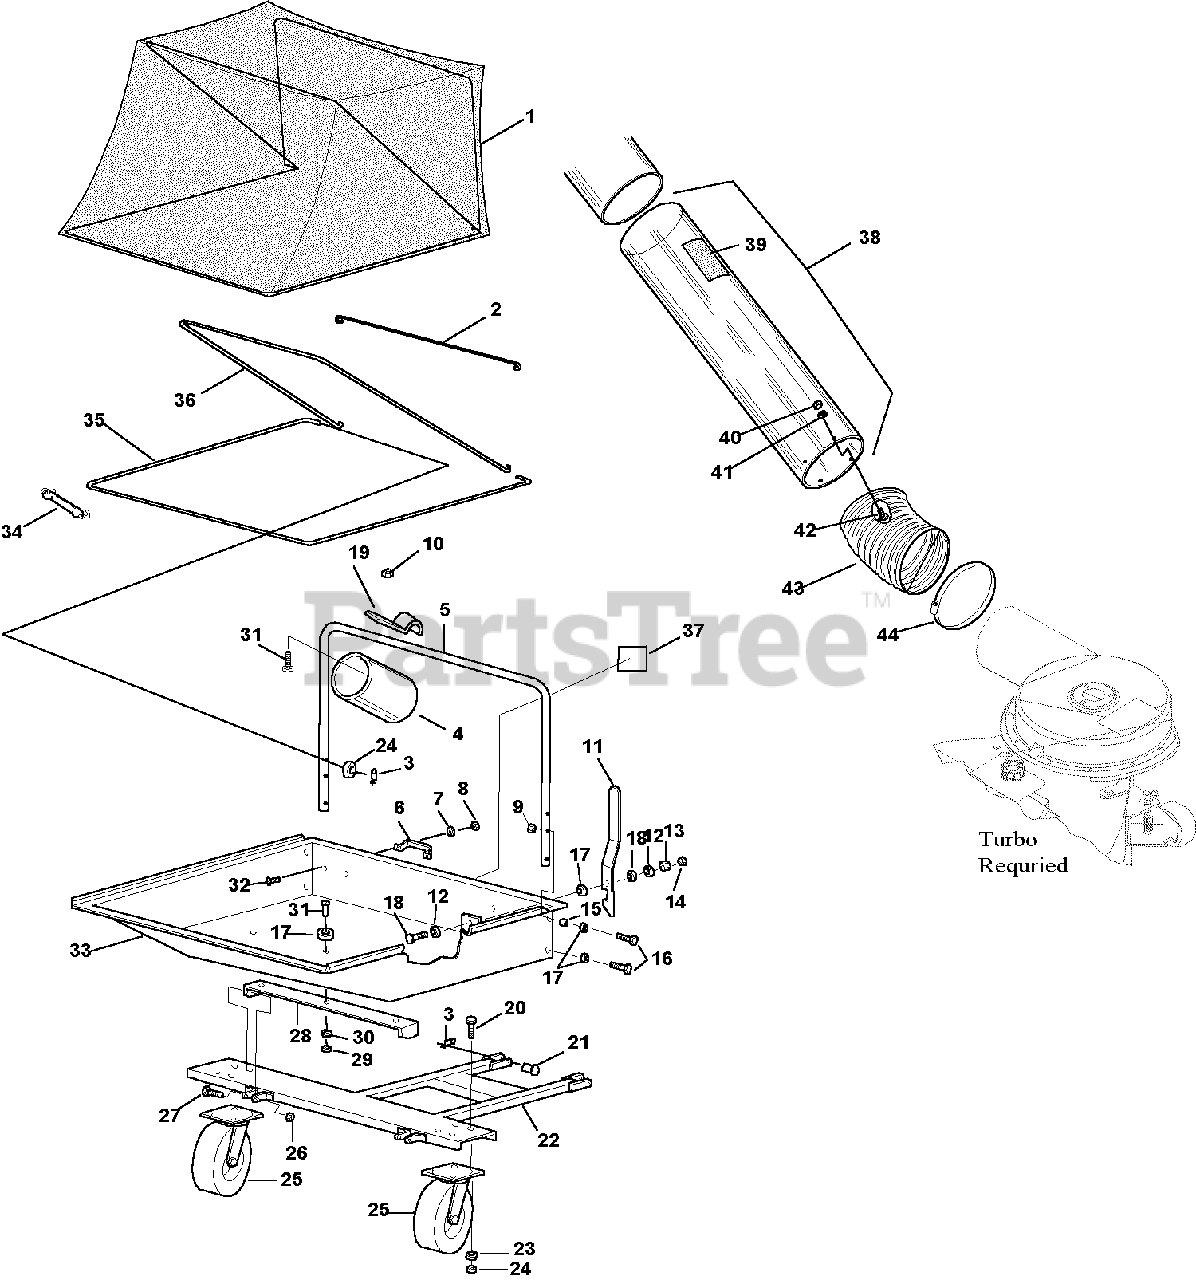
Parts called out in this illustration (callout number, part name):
1	COVER, Jrco, Cart
3	SAFETY, Pin
5	TUBE, Support
6	HANDLE, Lift
7	LOCKWASHER, Spring, 1/4-20
8	NUT, Hex, 1/4-20
9	NUT, Hex Centerlock, 5/16-18
10	NUT, Hex Nylock, 1/4-20
11	HANDLE, Latch
12	WASHER, Compression
13	NUT,Hex, 5/16-18
14	NUT, Hex Jam, 5/16-18
16	CAPSCREW, Hex Head, 5/16-18 X 1-1/2
17	WASHER, 5/16
18	CAPSCREW, Hex Head, 5/16-18 X 1-1/4
19	SLEEVE, Clamp
20	CAPSCREW, Hex Head 3/8-16 X 1
21	PIN, Rnd, Head, Drilled, 1/2 X 1-1/2
22	FRAME, Jrco, Cart
23	WASHER, 3/8
24	NUT, Hex Centerlock, 3/8-16
25	WHEEL Assembly, Swivel
26	NUT, Hex Centerlock, 1/2-13
27	CAPSCREW, Hex Head, 1/2-13 X 1-1/4
28	BRACKET, "U"
29	NUT, Hex, 5/16-18
30	LOCKWASHER, Spring, 5/16
31	SCREW, Truss Head Slotted, 5/16-18 X 3/4
32	CAPSCREW, Hex Head, 1/4-20 X 1/2
33	BOX, Jrco 44"
34	STRAP, Rubber
36	ROD, Support
37	DECAL, Maximum Capacity
38	TUBE & DECAL ASSEMBLY
39	DECAL, Cleaning Instructions
40	NUT, Hex Centerlock, #10-32
41	WASHER, Plain, #10-32
42	SCREW, Truss Head Phippils, #10-32 X 1/2
43	HOSE, Vac Col, 6 X 12
44	CLAMP, Hose 6", Band Type
